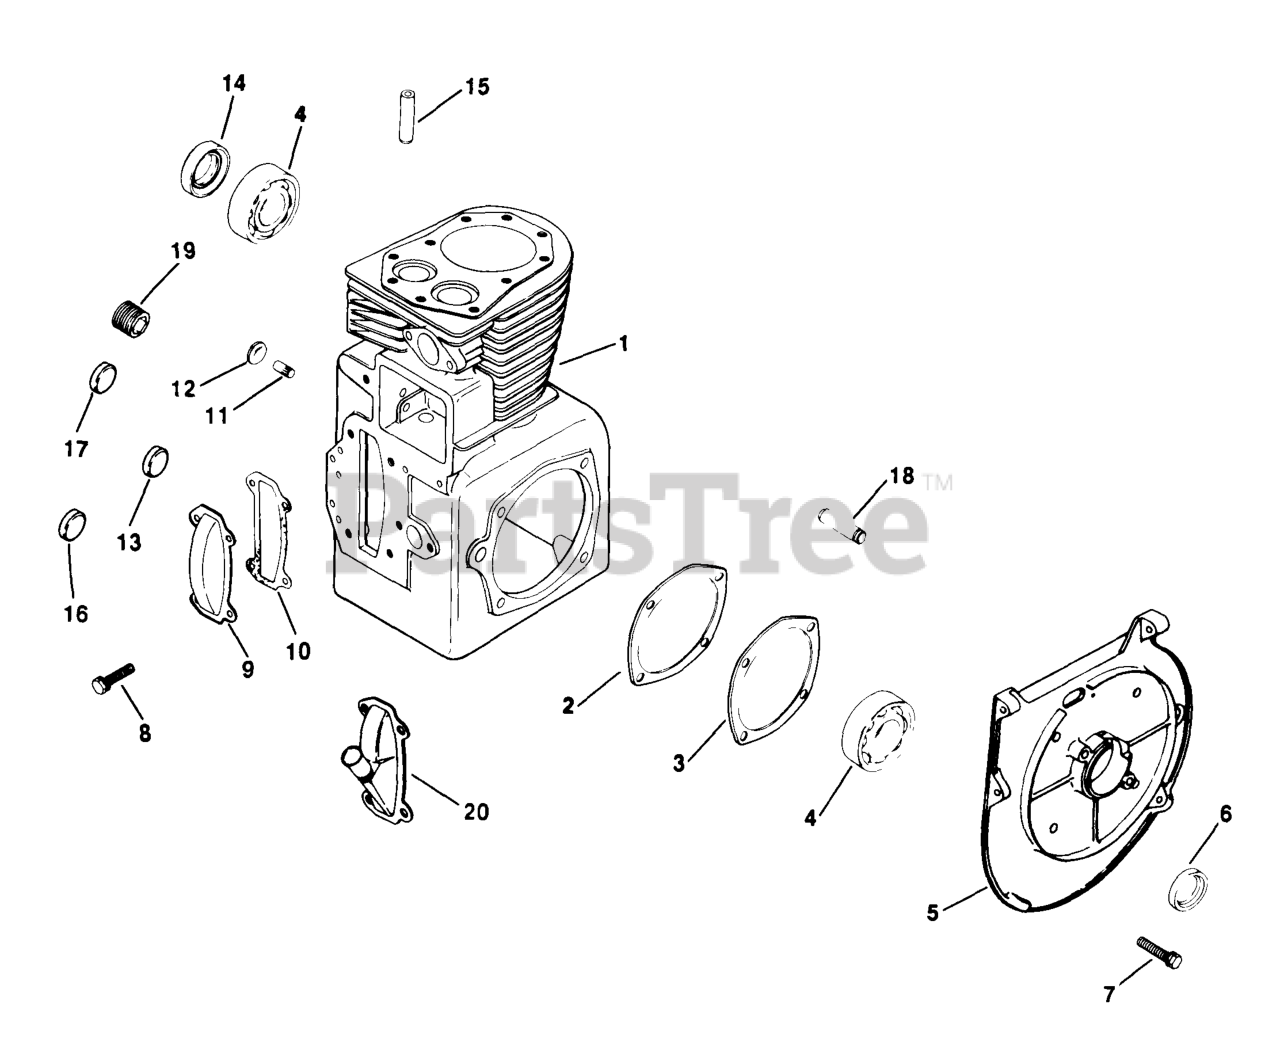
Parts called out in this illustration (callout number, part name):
1	Cylinder Block
3	GASKET, BEARING PLATE - DISCONTINUED
4	BEARING, BALL
5	PLATE, BEARING - DISCONTINUED
6	SEAL, FRONT OIL
7	SCREW, SEMS 3/8-16-X1"
8	SCREW, SEMS 1/4-20X5/8" USE 25 086 539-S
9	COVER, CAMSHAFT - DISCONTINUED
10	GASKET, CAMSHAFT COVER
11	SHAFT, GOVERNOR GEAR
12	PLUG, WELCH EXPANSION
13	PLUG, CUP 1/2" USE 25 139 50-S
14	SEAL, REAR OIL
15	GUIDE, VALVE - DISCONTINUED
16	PLUG, CUP USE 25 139 48-S
